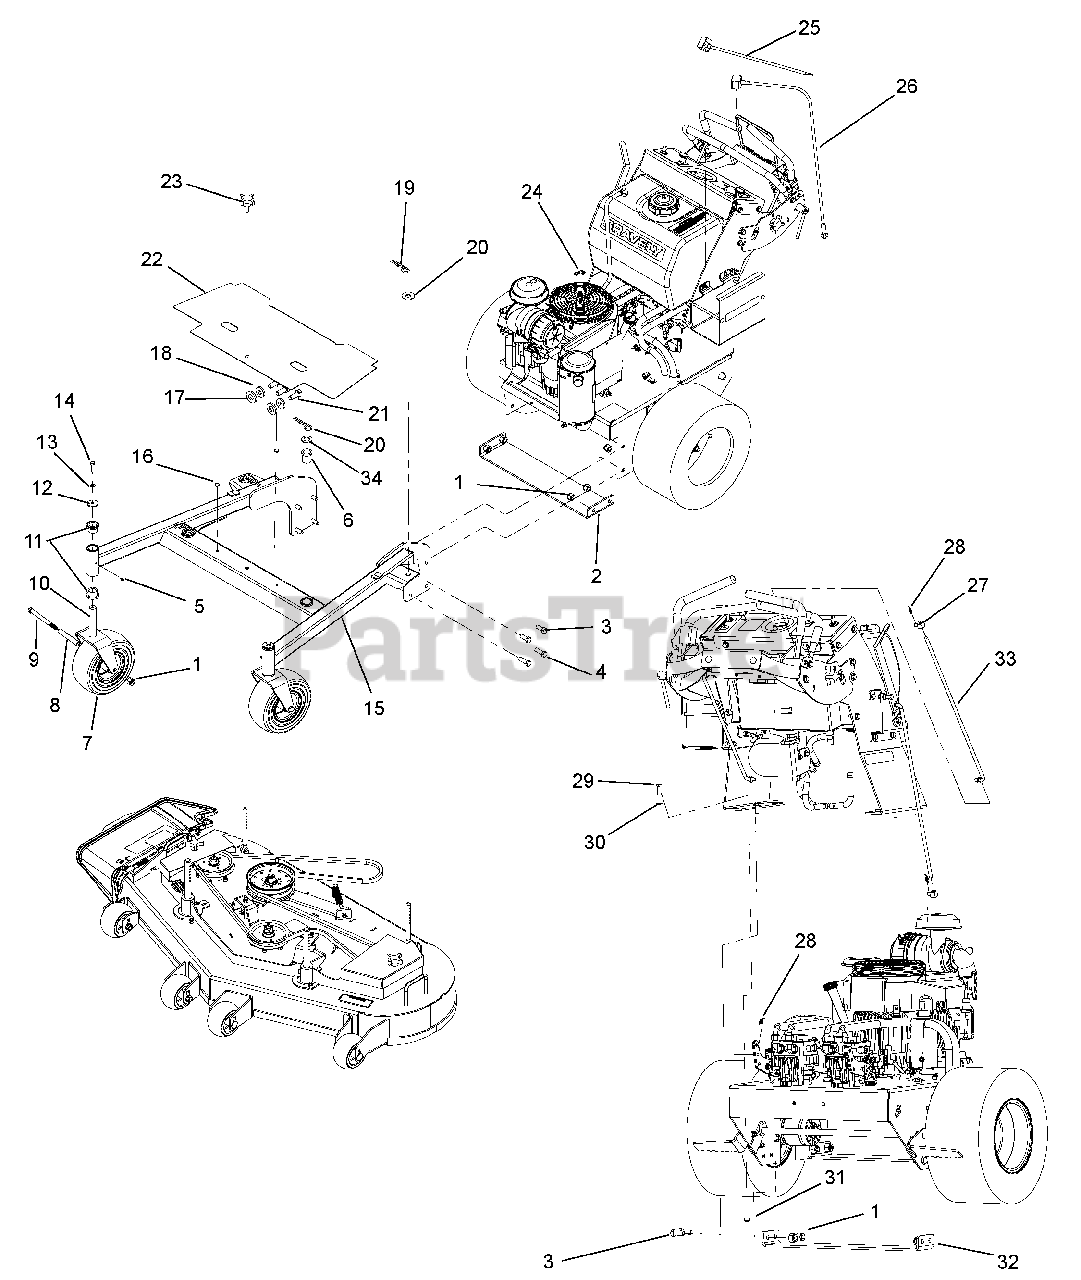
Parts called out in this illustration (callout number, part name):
1	LOCKNUT, 1/2-13 NYLOC Y
2	PLATE, ENGINE BED FRONT 48/52
3	BOLT, 1/2-13 X 1.25 HEX 5 Y
4	BOLT, 1/2-13 X 1.50 HEX 5 Y
5	FTG, 1/4-28 STRGT GREASE ZERK
6	BSHG, FLG 1.00 X 1.25 X 1.50 X 1.50 EP REV
7	ASSY, WHEEL & TIRE - 9X3.5-4
8	TUBE, CASTER AXLE
9	BOLT, 1/2-13 X 5.50 HEX 5 Y
10	WLDT, FRONT WHEEL FLOAT WALK
11	BRG, FLG 1.00X1.25X1.00
12	WSH-FL-ST .38 X 1.50 X .125 REV
13	WASHER, .375 MED SPRG LOCK Y
14	BOLT, 3/8-16 X 1.25 HEX 5 Y
15	WLDT, DECK FRAME 52 FLWLK (988148)
16	BUMPER GROMMET .125 X .25 REV
17	WASHER, .905 X 1.750X.250
18	WASHER, BLADE
19	WASHER, FLAT-STEEL .688 X 1.75 X.134 REV
20	PIN, HAIR-INTERNAL .17 X .68 X 3.50 REV B
21	BOLT, 5/8-11 X 1.50 HEX 8 Y
22	SHIELD, BELT 52 FLOAT WALK (988148)
23	KNOB, STAR 3/8-16 X 1.00
24	CABLE TIE, .15 X 8.50
25	CABLE, BATTERY GROUND 25"
26	CABLE, BATTERY -25" POSITIVE
27	SWIVEL, 3/8-24
28	RING, RUE .375 X .054 x 1.254
29	BOLT, 3/8-16 X 1.00 HEX 5 Y
30	WASHER, .406 X .813 X .065 FLAT Y
31	LOCKNUT, 3/8-16 NYLOC Y
32	PLATE, ENGINE BED REAR
33	ROD, DRIVE CONTROL FW
34	WASHER, FL-STL REV
